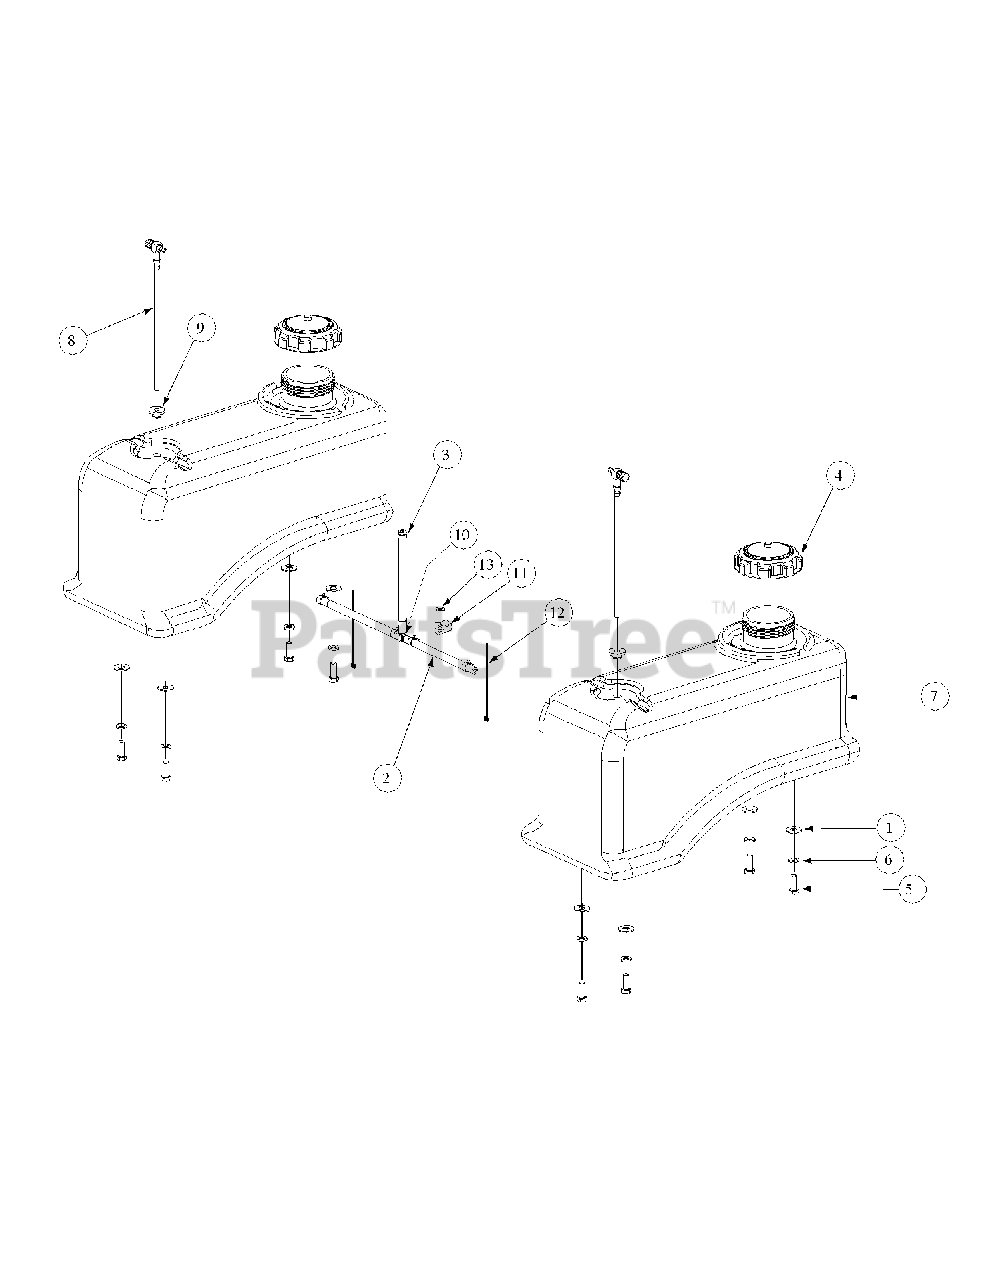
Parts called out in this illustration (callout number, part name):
1	Flat Washer, .406 ID, 1.0 OD, .105
2	Hose, 1/4" Fuel Line 79.5"
3	Clamp, Union
4	Fuel Cap, 3.5
5	Hex, Cap Screw, 3/8-16, .88
6	Lock Washer, 3/8
7	Fuel Tank
8	Fuel Fitting
9	Grommet, Fuel Tank
10	Tee Fitting, Fuel
11	Clamp, 1/2 Tubing
12	Cable Tie
13	Flat Washer, 1.4 x .630 x .0515
